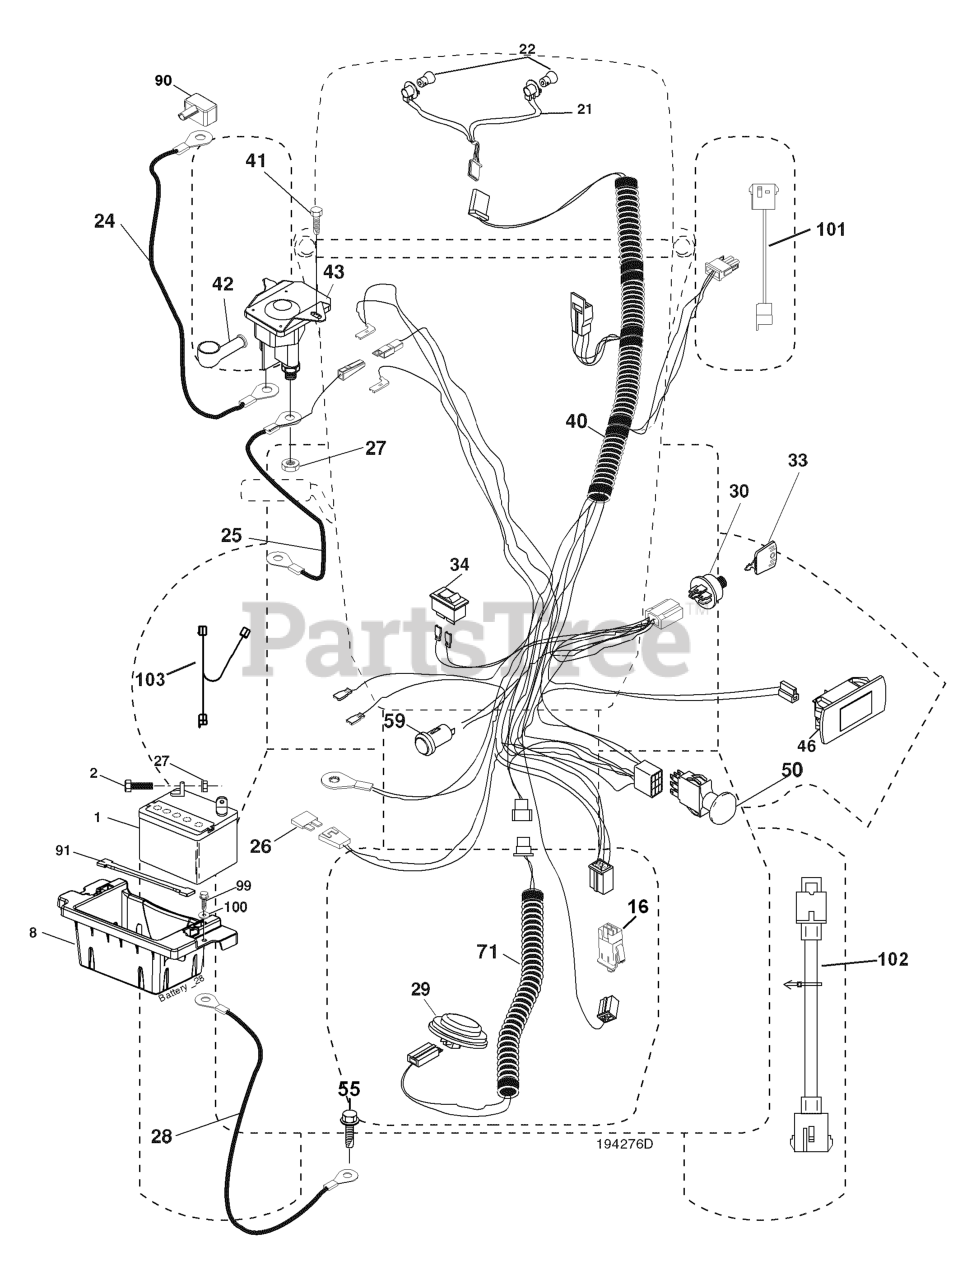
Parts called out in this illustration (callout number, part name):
1	BATTERY 12V .35 AMP
2	BOLT.HEX.1/4.X.3/4.DICHROMATE
8	BOX.BATTERY.MOUNT.FRONT.LT
16	SWITCH INTERLOOK PUSH-IN
21	HARNESS ASSY LIGHT
24	CABLE.BATT.POS.WIRE.TG.DA SOL
25	CABLE.START.RED.17.5".
26	FUSE 20AMP
27	NUT
28	CABLE GROUND 6 GA 21" 90T BLK
29	SWITCH.SEAT.DELTA.OPC.
30	SWITCH.IGN.DELTA.W.LGH.ROS
33	KEY MLD GEN DELTA
40	HARNESS.IGN.DASH.HUQ/P
41	SCREW
42	TERMINAL COVER
43	SOLENOID.W/BRASS.PLUNGER
46	RP.GUAGE.SRVCMNDR.HRMTR.
50	RP.PTO.SWITCH.8 TERMINAL.BLACK
55	SCREW.THDROL.5/16-18X3/4.TTY
59	OUTLET.12-VOLT
71	HARNESS-CHASSIS SUB
90	COVER.TERMINAL.BATTERY
91	STRAP.BATTERY.MOUNT.FRONT(2 2)
99	SCREW HEXWSHR 1/4-20X3/4
100	WASHER
101	PIGTAIL.MATNLK.NEW.HAR
102	HARNESS PIGTAIL PCH TEX ROS
103	HARNESS PIGTAIL 12V OUTLET
